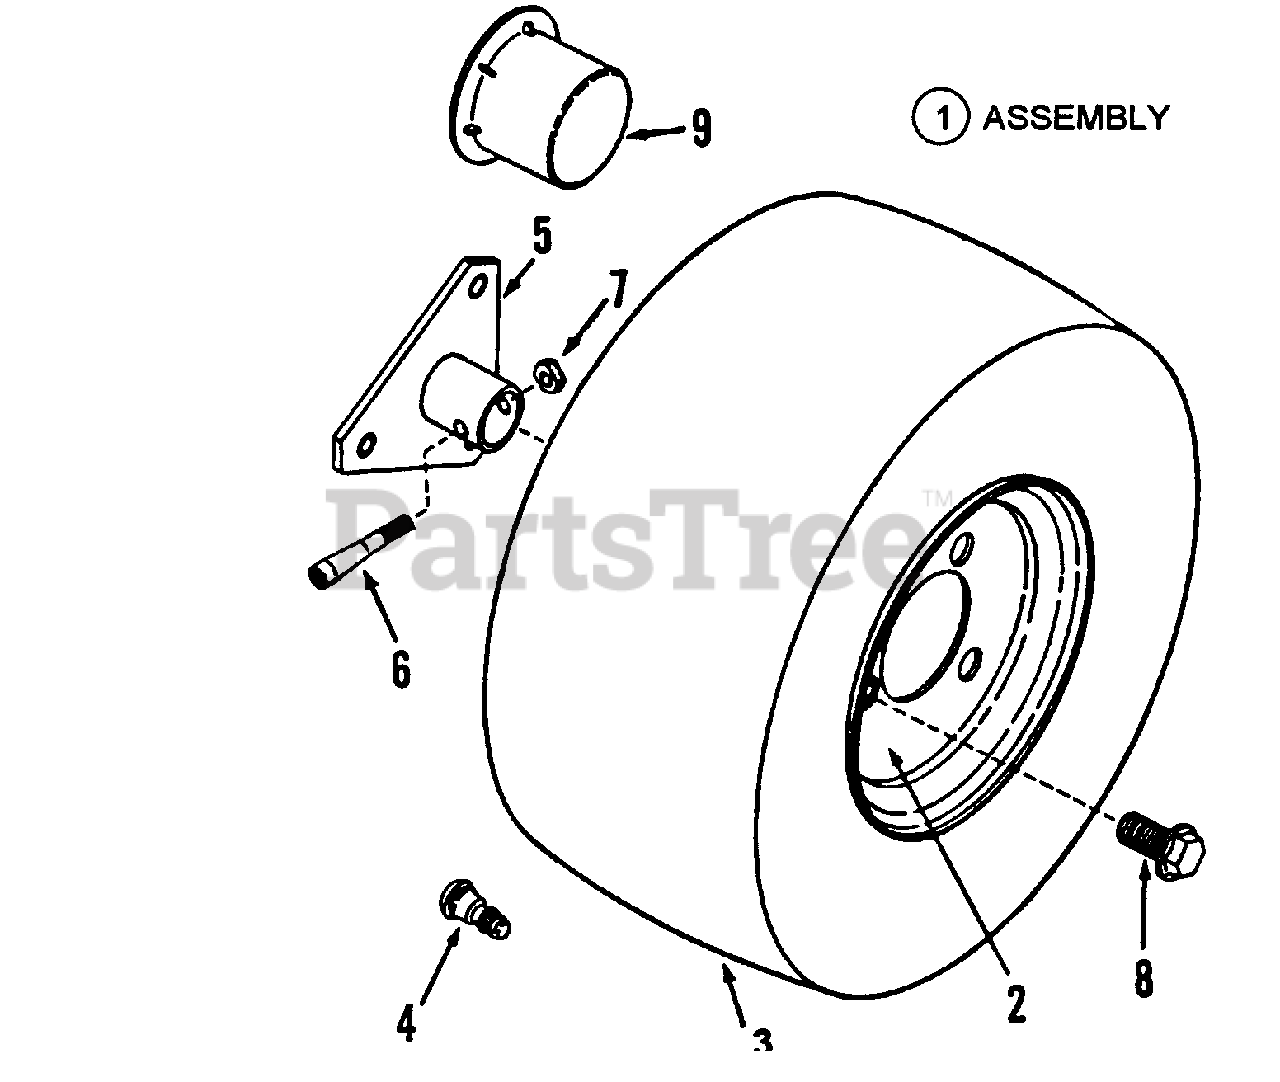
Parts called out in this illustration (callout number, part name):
1	* ASSEMBLY, Rear Tire & Rim (2 per tractor)(No longer available)
2	RIM, LT16 Rear Wheel (No longer available)
3	TIRE, 21 x 7.00 x 10 (No longer available)
4	VALVE, Air
5	HUB, Rear Wheel (1" Axle ID)(Weldment)
6	BOLT, Tapered
7	NUT, 5/16-24 Lock
8	BOLT, Lug (1/2-20 x 3/4" HHCS)
9	HUB-CAP
